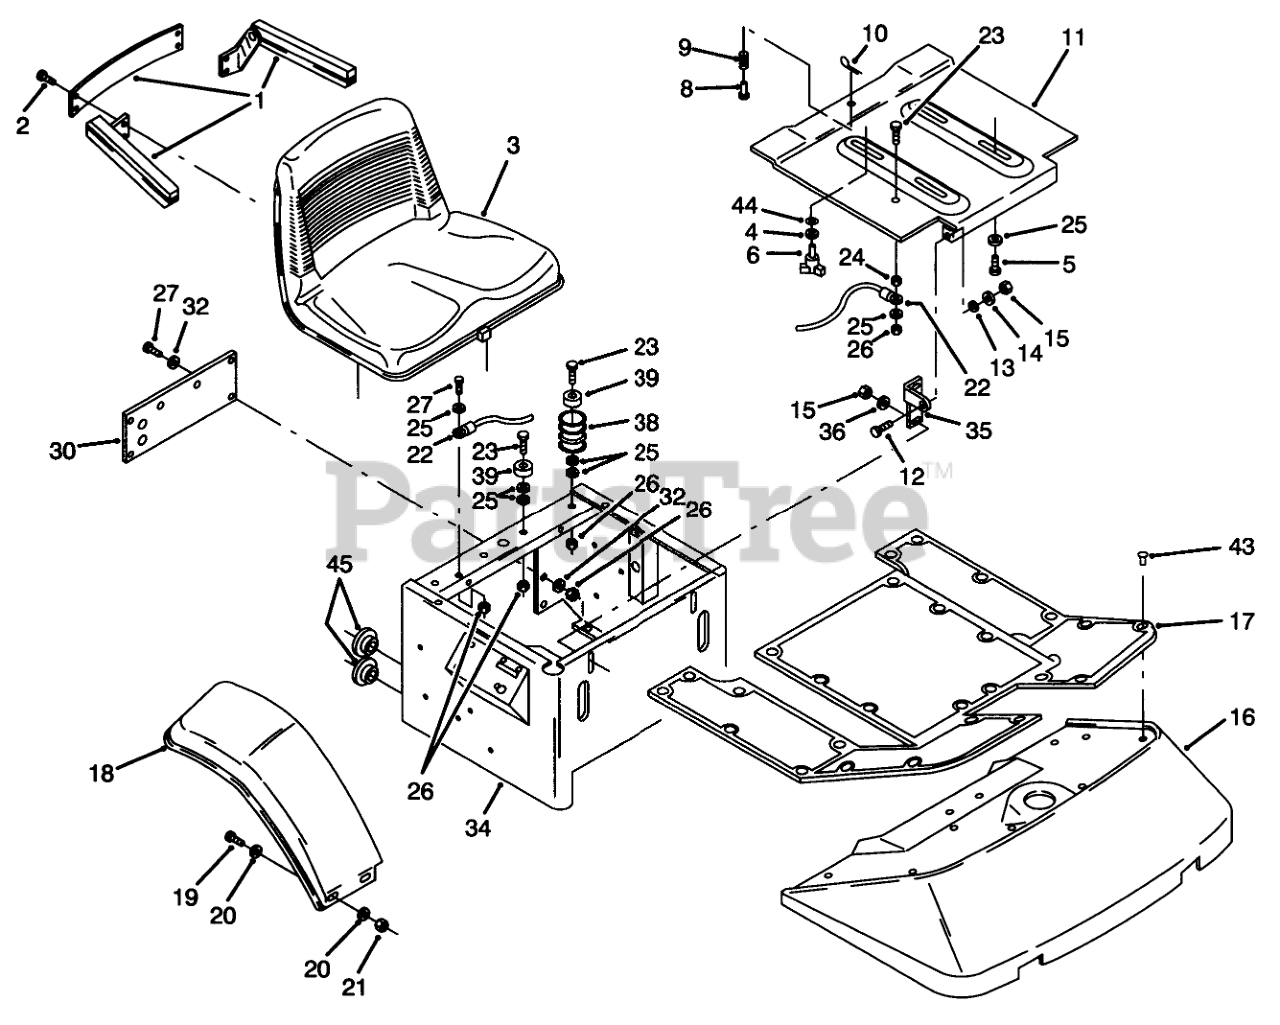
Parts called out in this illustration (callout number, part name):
1	KIT-ARMREST
2	Bolt
3	Seat
4	WASHER 5/16 SAE
5	BOLT 5/16-18X5/8
9	SPRING-COMPRESSION
10	PIN-COTTER
11	PLATE SEAT PIVOT R
12	BOLT-CARR
13	SPACER
14	WASHER-FLAT
15	NUT-LOCK, NI
16	Floor Pan
17	Black Mat
18	Fender RH
19	SCREW-HH
20	WASHER-FLAT
21	NUT-LOCK, NI
22	Cable
23	SCREW-HH
24	NUT-HEX
25	WASHER-FLAT
26	NUT-LOCK, NI
27	SCREW-HH
30	Cover
32	WASHER-PLAIN
34	SUPPORT-SEAT W A R
35	Seat Pivot Bracket RH
36	WASHER-FLAT
38	Spring-620-Z
39	BUMPER
43	RIVET .25 PLASTIC
44	LOCKWASHER INT EXT
45	BUSHING-NYLON 1.500
